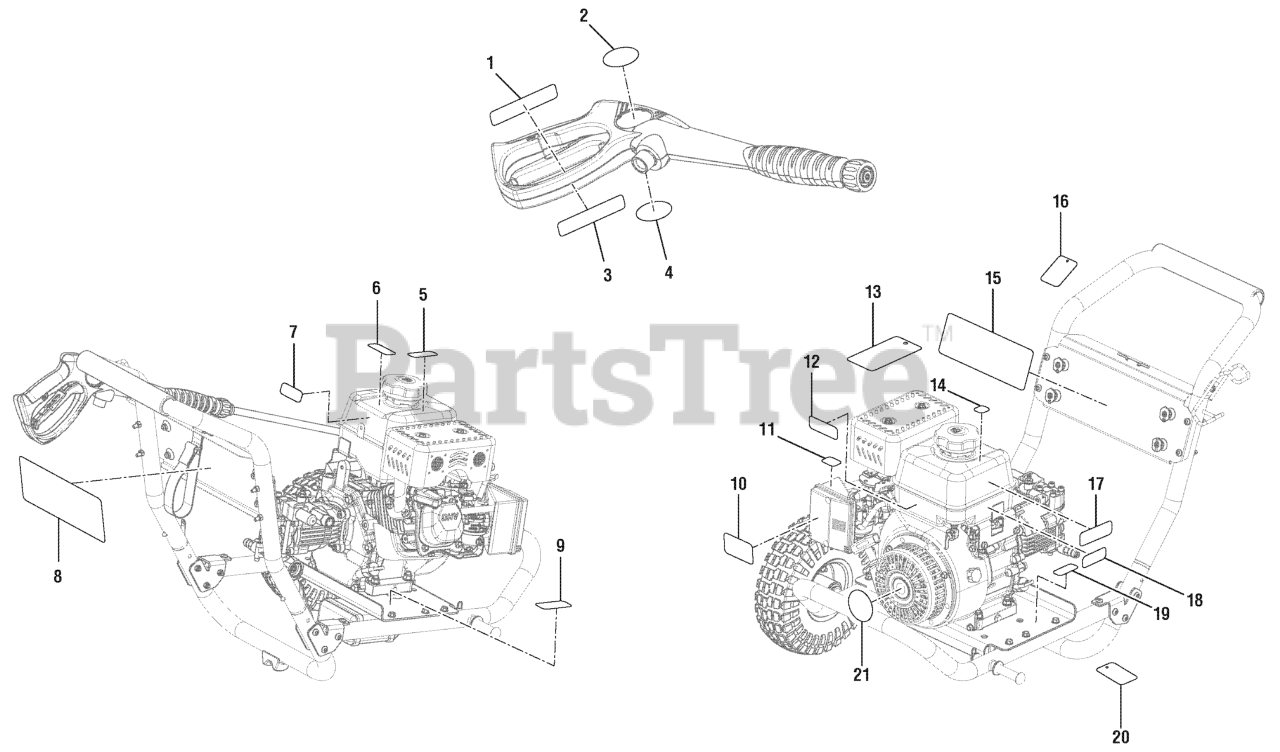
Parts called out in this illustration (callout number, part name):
1	TRIGGER HANDLE RATING LABEL
2	TRIGGER HANDLE LOGO LABEL
3	TRIGGER HANDLE WARN LABEL-FRSP
4	TRIGGER HANDLE WARN LABEL(ENG)
5	HOT SURFACE LABEL
6	DO NOT MIX LABEL
7	DANGER LABEL (FR)
8	QUICK START LABEL
9	COMBUSTION WARNING LABEL
10	LOGO LABEL
11	CHOKE LABEL
12	EMC LABEL
13	HANG TAG (ENGINE)
14	E-85 LABEL
15	PERFORMANCE LABEL
16	NOZZLE HANG TAG
17	DANGER LABEL (ENG)
18	FUEL VALVE LABEL
19	ADD OIL LABEL
20	OIL DIPSTICK HANG TAG
21	RECOIL LABEL
